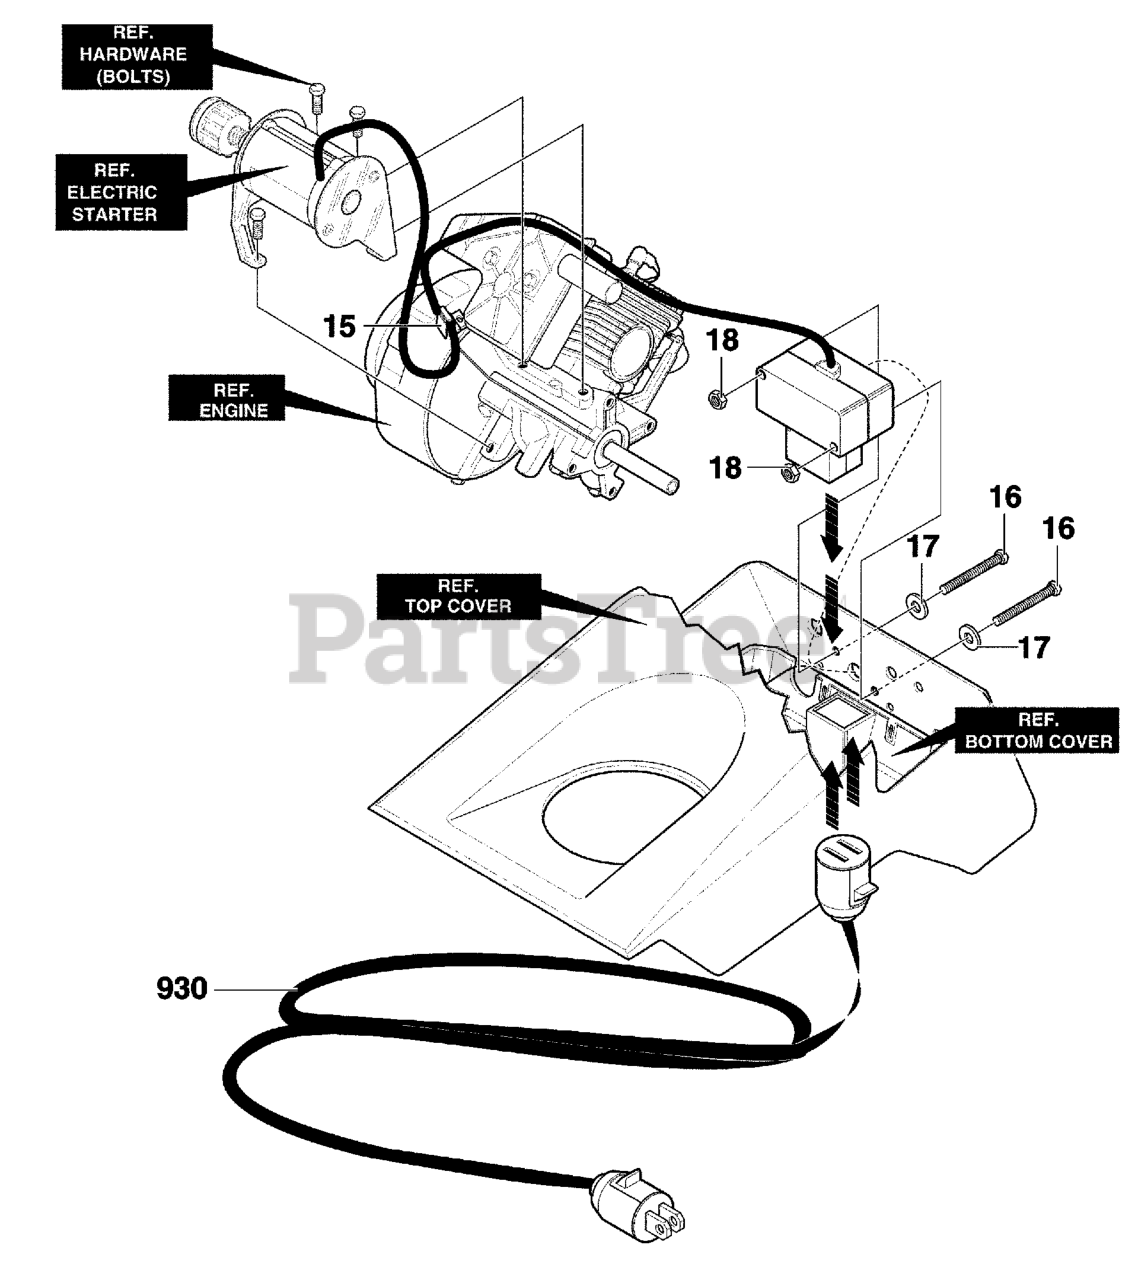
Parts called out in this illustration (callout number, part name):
15	RETAINER
16	SCREW #8-32X3.00
17	WASHER, FLAT .188X.38X.040
18	NUT, #8-32X3.00
930	CORD EXTENSION
